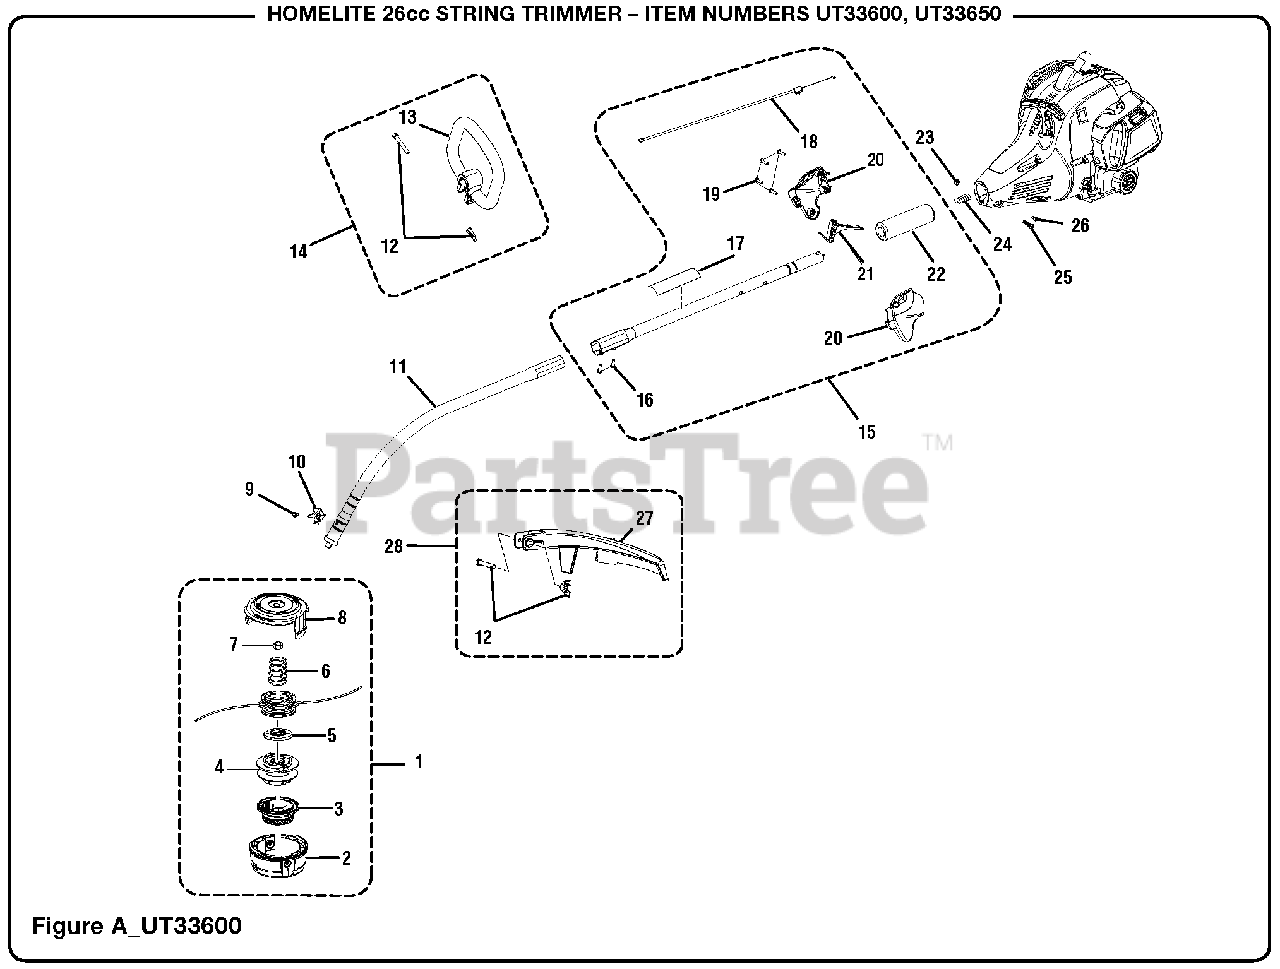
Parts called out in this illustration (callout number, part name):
1	Trimmer Head Assembly
2	Lower Housing
3	Bump Knob (Gray)
5	String Guide
6	Compression Spring
7	Hex Nut (M8)
8	Upper Housing
9	Screw (10-32 x 3/8 in., Hex Hd.)
11	Lower Boom Assembly
12	Fastener Kit
13	Front Handle
14	Front Handle Assembly
15	Boom Assembly
16	Screw (M5 x 10 mm, Hex. Soc. Hd.)
17	Icon Warning Label
18	Throttle Cable
19	Screw (M4 x 20 mm, T20 Torx Pan Hd. T.F.)
20	Trigger Handle Assembly
21	Throttle Trigger
22	Foam Grip
23	Hex Nut (M6)
24	Compression Spring
25	Screw (M6 x 20 mm, T27 Torx Button Hd.)
26	Screw (M4 x 8 mm, T20 Torx Round Hd.)
27	Grass Deflector
28	Grass Deflector Assembly
